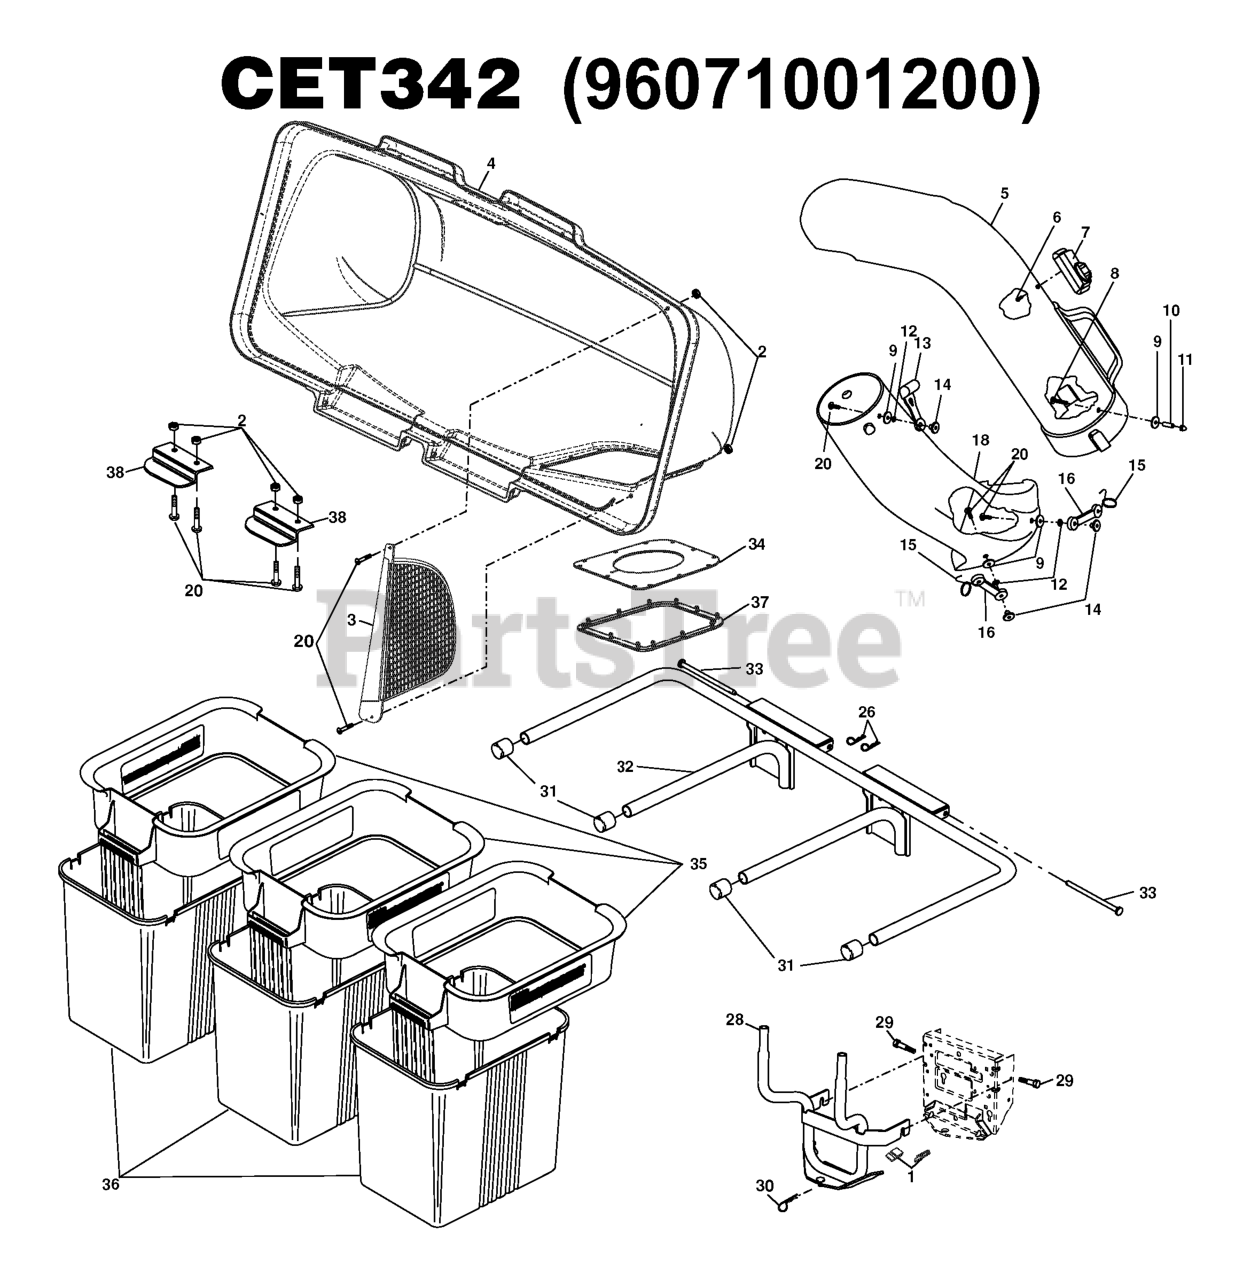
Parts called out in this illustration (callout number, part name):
1	ADAPTER.LT.3-BIN.QA.TEX
3	SCREEN.COVER.BAGGER
4	COVER.ASM.3BIN.GENERIC.
5	CHUTE.UPPER.42"
7	INDICATOR ASM BAG
8	SCREW
11	NUT
12	LOCKWASHER #10
13	LATCH.HOOD.
14	WELDNUT
15	HOOK LATCH
16	RUBBER LATCH
18	LOWER CHUTE FOR 42" BAGGER
20	SCREW
26	RETAINER-SPRNG RB
28	BRACKET.BAGGER.3-BIN.BLACK
29	SHOULDER BOLT, SELF-TAP
30	SPRING.RETAINER.YELLOW.ZINC
31	PLUG, TUBING END
32	BAGGER.ASM.FRAME.3BIN.BLACK
33	BAGGER.HINGE.PIN
34	SEAL.BAGGER.TOP.3-BIN.BLK
35	CONTAINER TOP
36	CONTAINER BOTTOM
37	GASKET.COVER.BAGGER
38	LATCH CER38
